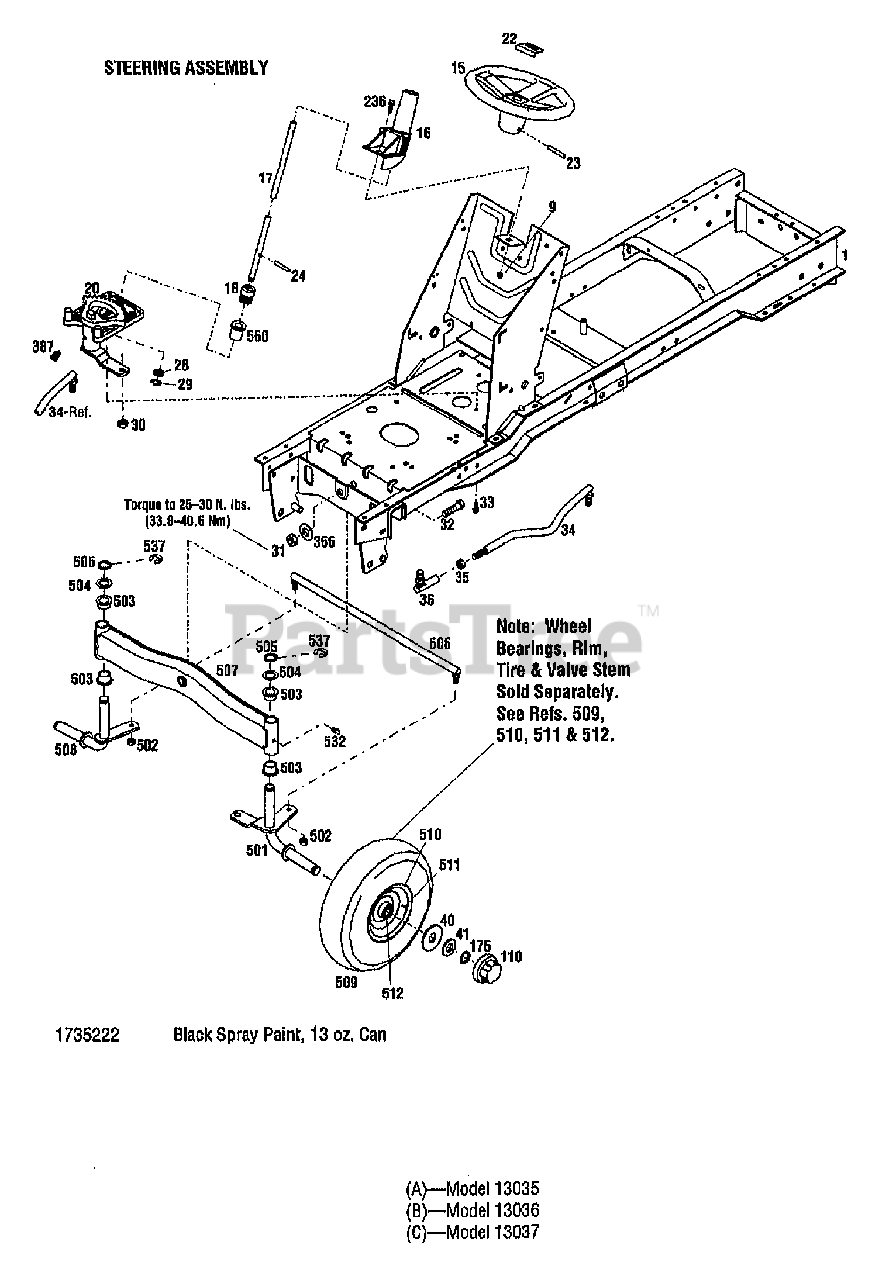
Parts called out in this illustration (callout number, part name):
1	ASSM-FRAME LTX
9	NUT-HFLK 5/16-18 ZP
15	WHEEL-STEERING
16	SUPPORT-STEERING SHAFT
17	SHAFT-STEERING
18	GEAR-PINION
20	ASSM-STEERING GEAR
22	CAP-STEERING
23	PIN-ROLL .25X2.25
24	PIN-ROLL 1/4 X 1-1/4
28	WASHER-1.0X.64X.09
29	RING-RETAINING
30	NUT-HEX/JAM 1/2-20
31	NUT-H/LK 5/8-11
32	SCR-HH
33	SCR-HFLK 5/16-18X.75
34	LINK-DRAG
35	NUT-JAM
36	JOINT-BALL
40	WASHER-SPEC .75X2.50
41	WASHER-1.38 X.765X .06 ZP
110	CAP-HUB
175	RING-RET."E".577 ID
236	SCR-HFLK 5/16-18X.75 ZP
366	WASHER-1.75X.687X.134 ZP
387	FITTING-GREASE 90 DEGREE
501	ASSM-SPINDLE LH
502	NUT-LOCK
504	WASHER-1.25X.765X.049
505	RING-HEAVY EXT HD 1.0 ID
508	ASSM-SPINDLE WHEEL RH
509	TIRE 15X6.00-6RS
510	DISC WHEEL
511	STEM-VALVE
512	BEARINGS-WHEEL
532	FITTING-GREASE 1/4-28X2.00
537	RING-RET."E".577 ID
550	BEARING
